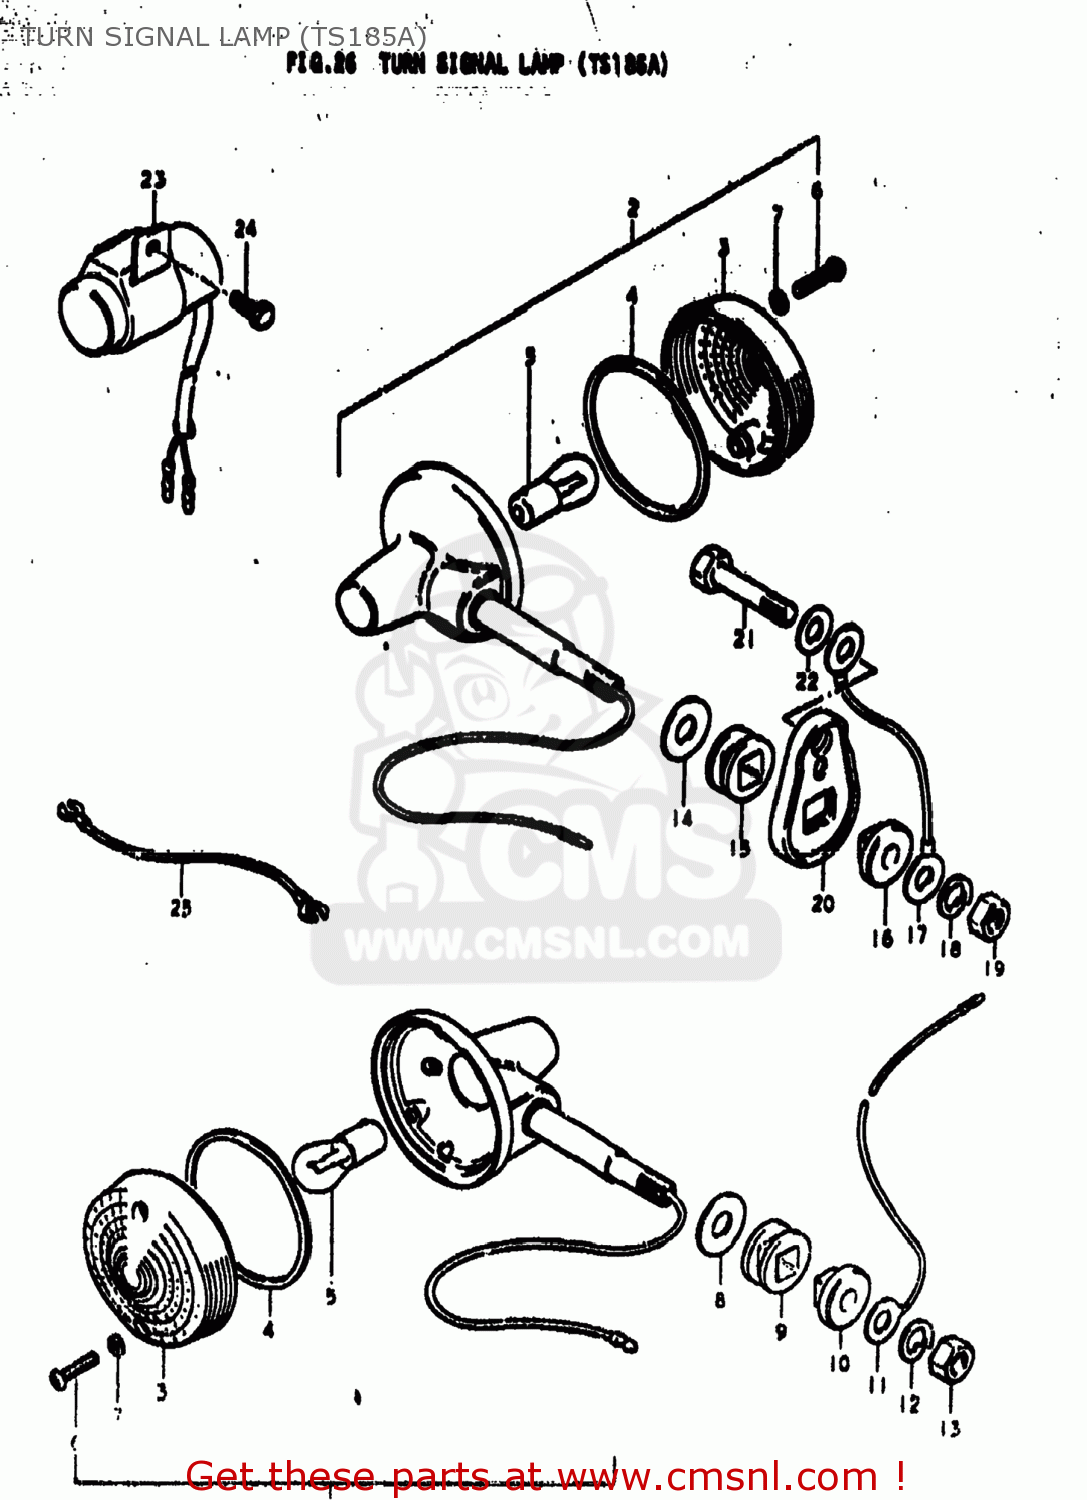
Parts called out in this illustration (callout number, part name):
1	LAMP ASSEMBLY,FRONT TURN SIGNAL
2	LAMP ASSEMBLY,REAR TURN SIGNAL
3	LENS
4	GASKET (NAS)
5	BULB(6V17W,STANLEY,A4513A)
6	SCREW
7	GASKET (NAS)
8	WASHER (10.5X30X2.3)
9	CUSHION
10	SPACER,RR TURNSIGNAL LAMP
11	LEAD WIRE,EARTH
12	LOCK WASHER
13	NUT
14	WASHER(10.5X20X3.2)
15	CUSHION
16	SPACER,RR TURNSIGNAL LAMP
17	WIRE
18	LOCK WASHER
19	NUT
20	BRACKET,TURN SIGNAL
21	BOLT 10X50
22	WASHER
23	RELAY,TURN SIGNAL
24	BOLT(6X8)
25	WIRE
